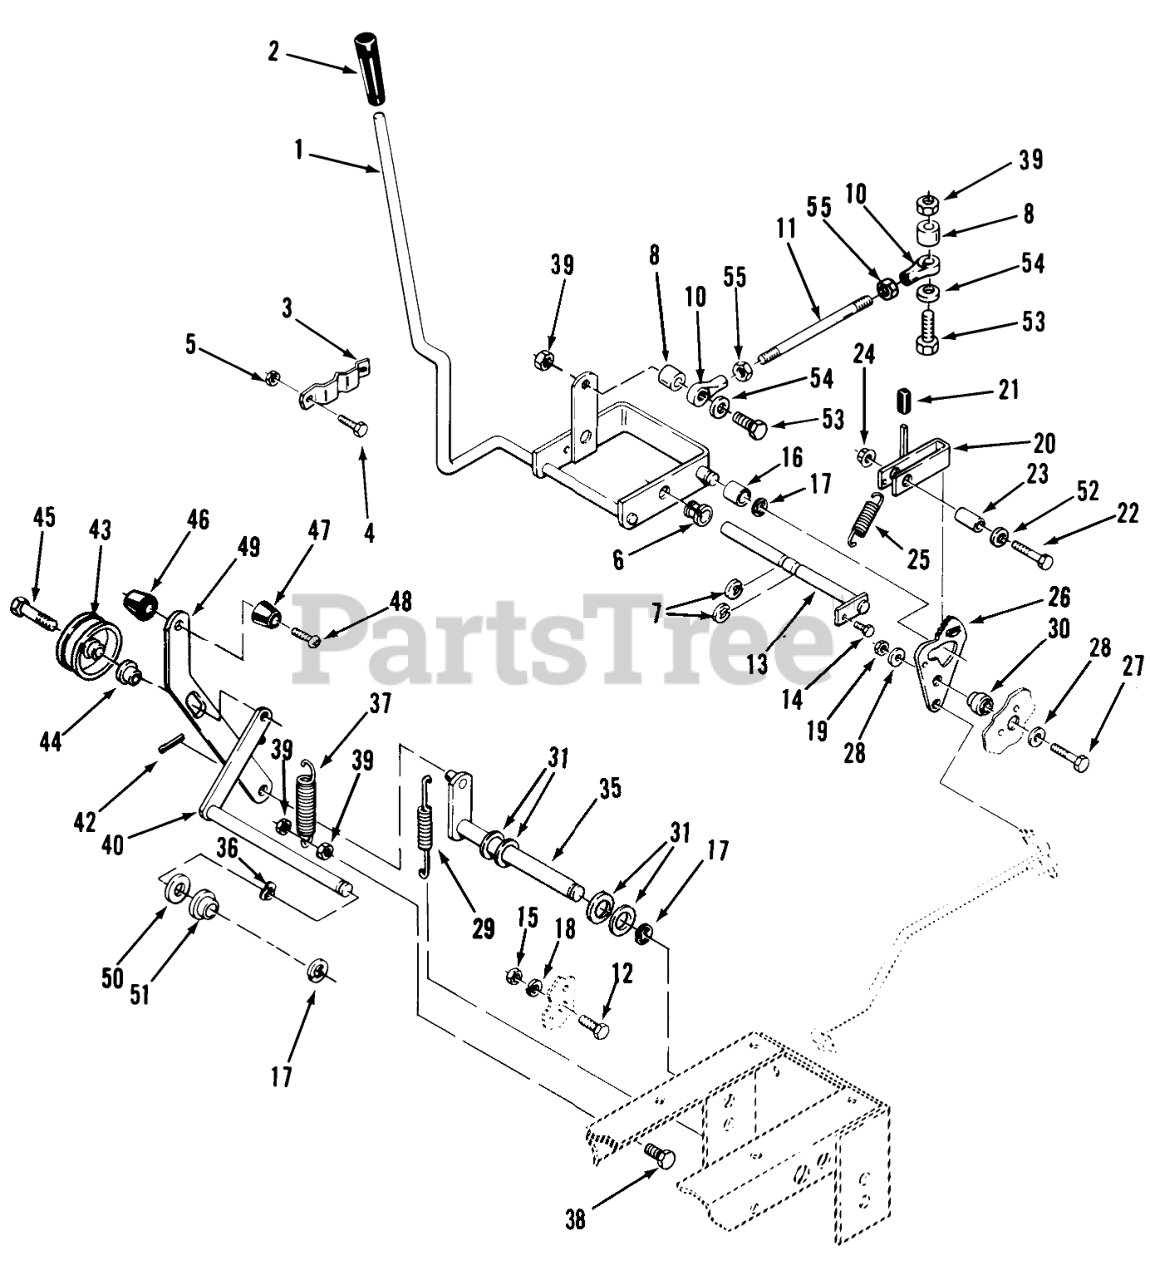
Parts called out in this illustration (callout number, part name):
1	Motion Control Lever
2	KNOB
3	Detent-Motion Control Lever
4	H H C S
5	Nut
6	NYLINER BUSHING
7	E Ring
8	Spacer
10	ASSY ROD END
11	ROD CONTROL
11	ROD-CONTROL
12	Bolt
13	ASSY-ROD CAM PIVOT
14	SCREW
15	Nut
16	BEARING-CAM RETURN
17	E Ring
18	LOCKWASHER
19	Nut
20	PAWL HDL ASSY B
21	VALVE LEVER GRIP
22	Bolt
23	SPACER
24	LOCKNUT-FLANGE
25	Spring
26	Cam Plate
27	Bolt
28	Washer
29	SPRING-EXTENSION
30	Spacer
31	Washer
35	ASSY-BRAKE LEVER
36	WASHER-WAVE
37	SPRING-EXTENSION
38	Bolt
39	Nut
40	ASSY-ARM/ROD WA
42	Cotter Pin
43	PULLEY-IDLER
44	SPACER-BRAKE LINK
45	BOLT-SPECIAL HEX
46	KNOB
47	KNOB
48	BOLT-4
49	Handle
50	Washer
51	BUSHING-FLANGED
52	Washer
53	Bolt
53	Bolt 1/4-20 X 1 1/2
55	Jam Nut 1/4-28
